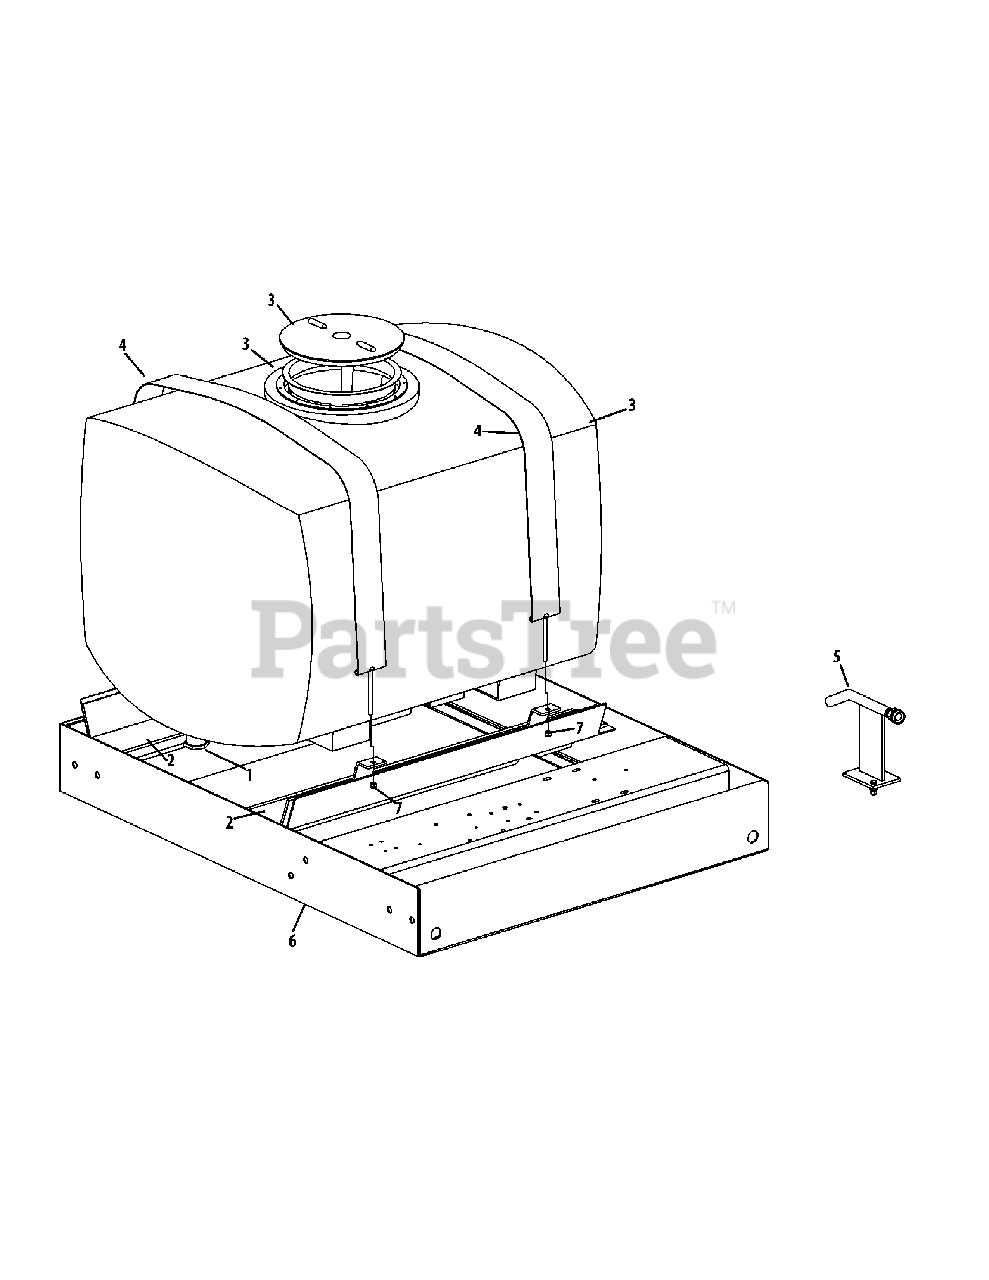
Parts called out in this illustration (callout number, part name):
1	PVC Adapter, 1.25 x 1
2	Adhesive Backed Foam, 1/4 x 4
3	100 Gallon Poly Tank
4	Tank Strap
5	Air Gap Filler
7	Hex Lock Nut, 5/16 -18
